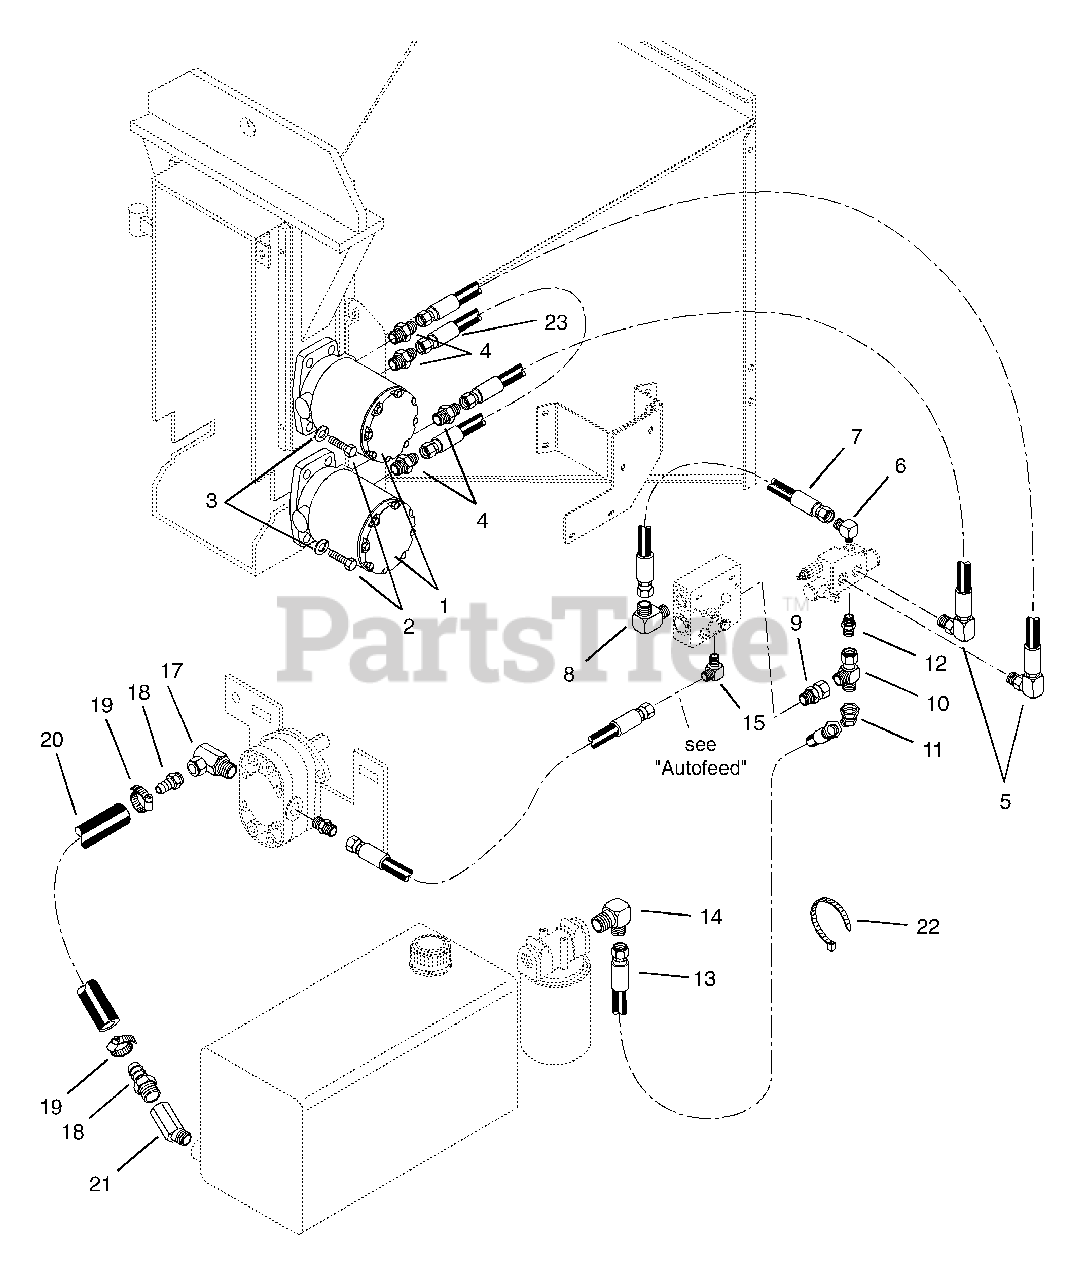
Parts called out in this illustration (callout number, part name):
1	Motor-Hydraulic
2	Bolt-Hex .50-13 x 1.25 Grade 5
3	Washer-Locking .50 x .125
4	Adapter-Hydraulic Straight 7.8 inch "O" inch to 3/4
5	Hose-Hydraulic 40 inch w/90 Degree Swivel
6	Adapter-Hydraulic Elbow 3/4 "O" to 3/4
7	Hose-Hydraulic Flow
8	Adapter-90 Degree Swivel
9	Fitting-Hydraulic
10	Tee-Swivel
11	Elbow-Swivel 45 Degree
12	Adapter-Hydraulic Straight 3/4 inch "O" inch to 3/4
13	Hose-Hydraulic 65.62 inch Steel
14	Fitting-Hydraulic
15	Fitting-Hydraulic
16	Hose-Hydraulic 63 inch
17	Elbow-90 Degree w/O-Ring NPSM
18	Adapter-Barbed Insert
19	Clamp-Hose-Water 1-3/16 to 1 3/4
20	Hose-Hydraulic
21	Adapter-Pipe
22	Tie Wrap
23	Hose-Hydraulic 32.62 inch Straight
